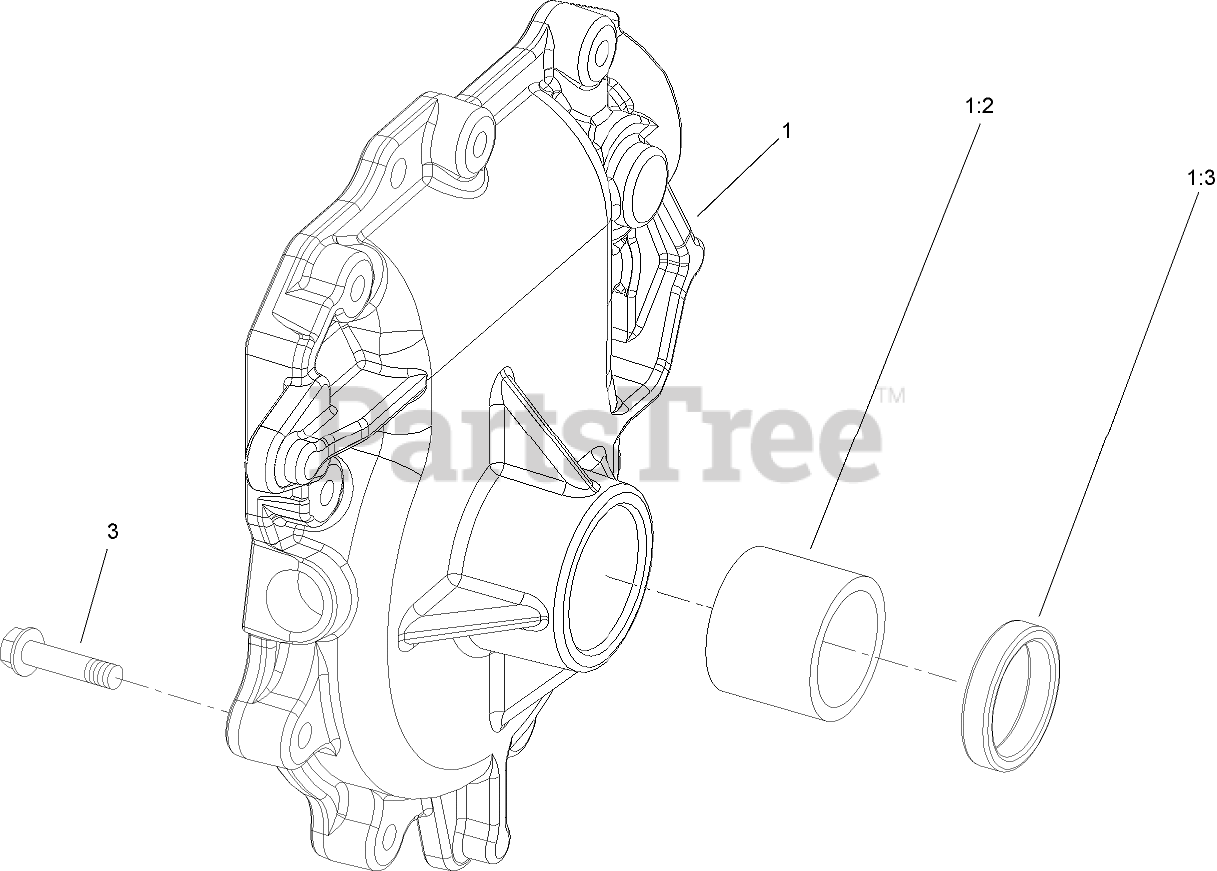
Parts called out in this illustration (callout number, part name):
1	L.H. AUGER GEARCASE ASM
1:2	BUSHING
1:3	SEAL-OIL
3	SCREW-HWHTF
